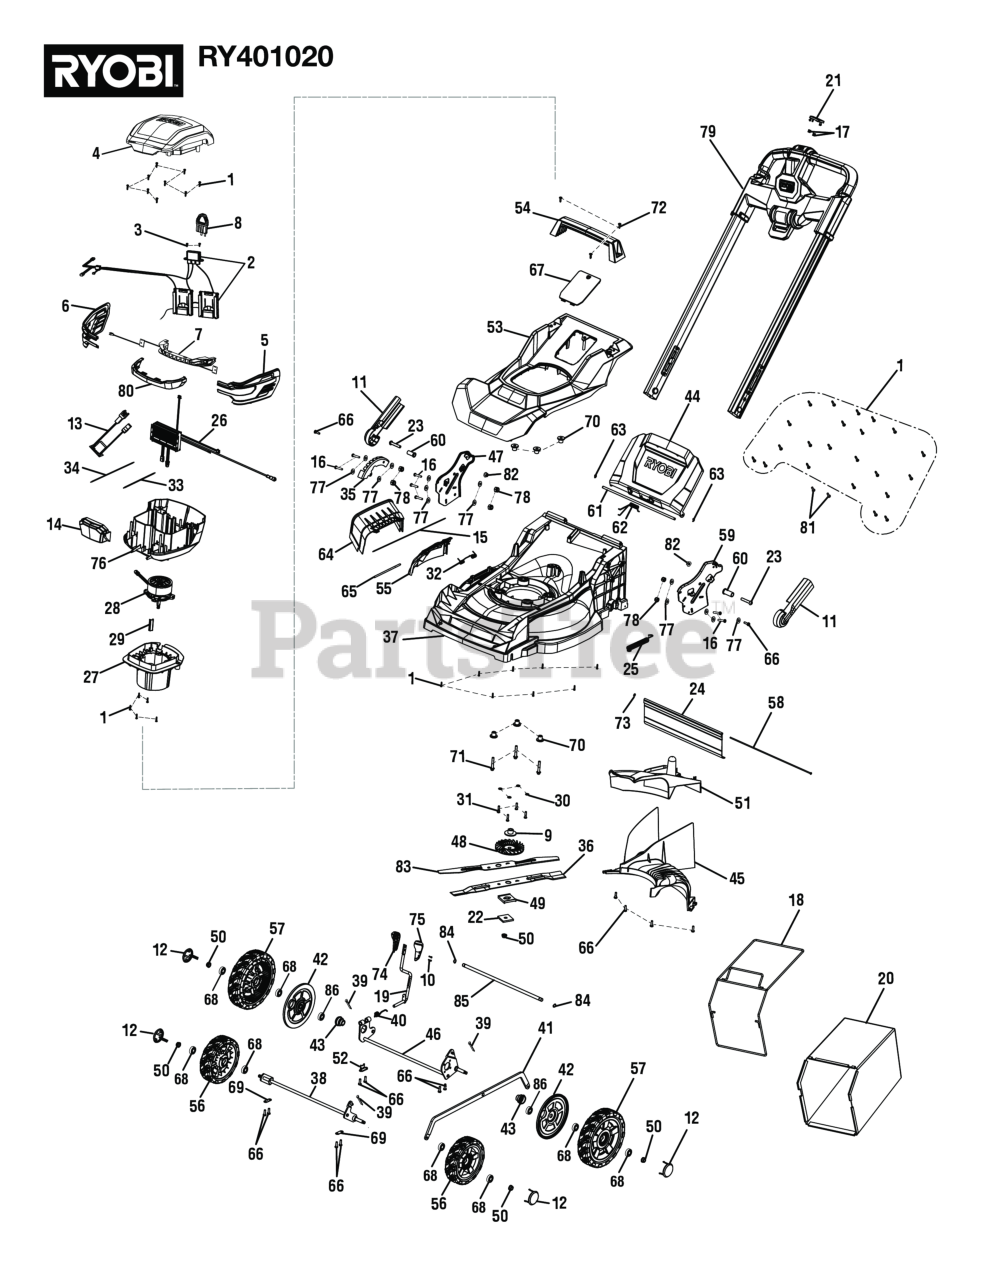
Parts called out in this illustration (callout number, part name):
1	Screw (M4 x 18 mm, T20 Torx Pan Hd.)
2	Key Base and Battery Foot Assembly
3	Screw (M4.2 x 12 mm, T20 Torx Pan Hd.)
4	Battery Housing Top Cover with Labels
5	Battery Housing Front Vents (Left)
6	Battery Housing Front Vents (Right)
7	LED Circuit Board Assembly
8	Start Key Assembly
9	Motor Shaft Bushing
10	Screw (M3 x 12 mm, Pan Hd.)
11	Hinge Cover
12	Wheel Hub Cap
13	Control Board Assembly
14	Battery Housing Front Plug Cover
15	Electric Wire with Terminal (22 AWG)
16	Screw (1/4-20UNC X 31.75 in., T30 Torx Pan Hd.)
18	Grass Bag Frame
19	Height Adjustment Handle
20	Grass Bag
21	Blade Button
22	Blade Spacer Metal Plate
23	Screw (M10 x 48 mm, Hex. Recess Hd.)
24	Trailing Shield
25	Compression Spring
26	Motor Controller
27	Motor Bucket
29	Wire Harness Cover
30	Washer (ID6.2 x OD15 x 0.08t)
31	Bolt (M6 x 26 mm, Hex Hd.)
32	Mulch Cover Spring
33	Red Lead Wire (14 AWG, 215 mm)
34	Black Lead Wire (14 AWG,280 mm)
35	Height Adjustment Bracket
37	Deck Assembly (Inc. Labels)
38	Front Axle
39	Cotter PinÏ? (2.5)
40	Torsion Spring
42	Wheel Cover
43	Transmission Bearing Bushing
44	Rear Door
45	Discharge Baffle
46	Rear Axle
47	Handle Bracket (Right)
48	Motor Fan Blade Adapter
49	Plastic Blade Spacer
50	Blade Nut (M10 x 1.25, Hex Flange Hd.)
51	Mulching Plug
52	Rear Axle Press Plate
53	Top Cover with Labels
55	Side Discharge Door
56	8 in. Wheel Assembly
57	10 in. Wheel Assembly
58	Trailing Shield Pin
59	Handle Bracket (Left)
60	Handle Bushing
61	Rear Door Axle
62	Rear Door Torsion Spring
63	Retaining Ring (E)
64	Side Charge Deflector
65	Hinge Rod
66	Screw (1/4-15 x 3/4 in., T30 Torx Pan Hd.)
67	Top Cover Door
68	Ball Bearing (ID12 x OD32 x 10 mm)
69	Front Axle Press Plate
70	Engine Spacer
71	Screw (M8 x 50 mm, Hex Hd.)
72	Screw (10-14 x 19 mm, T25 Torx Truss Pan Hd. T.F.)
73	Retaining Ring
74	Height Adjustment Knob (Right)
75	Height Adjustment Knob (Left)
76	Battery Housing Bottom
77	Washer (1/4 in.)
78	Lock Nut (1/4-20 in.)
79	Handle Assembly
80	LED Clear Window Lens
81	Screw (M4 x 10 mm, T20 Torx Pan Hd.)
82	Center Lock Nut (M10)
83	21 in. Top Blade, Stepped
84	Retaining Ring
85	Rear Axle Cross Shaft
86	Ball Bearing (OD28.6 x ID12.7 x 8)
